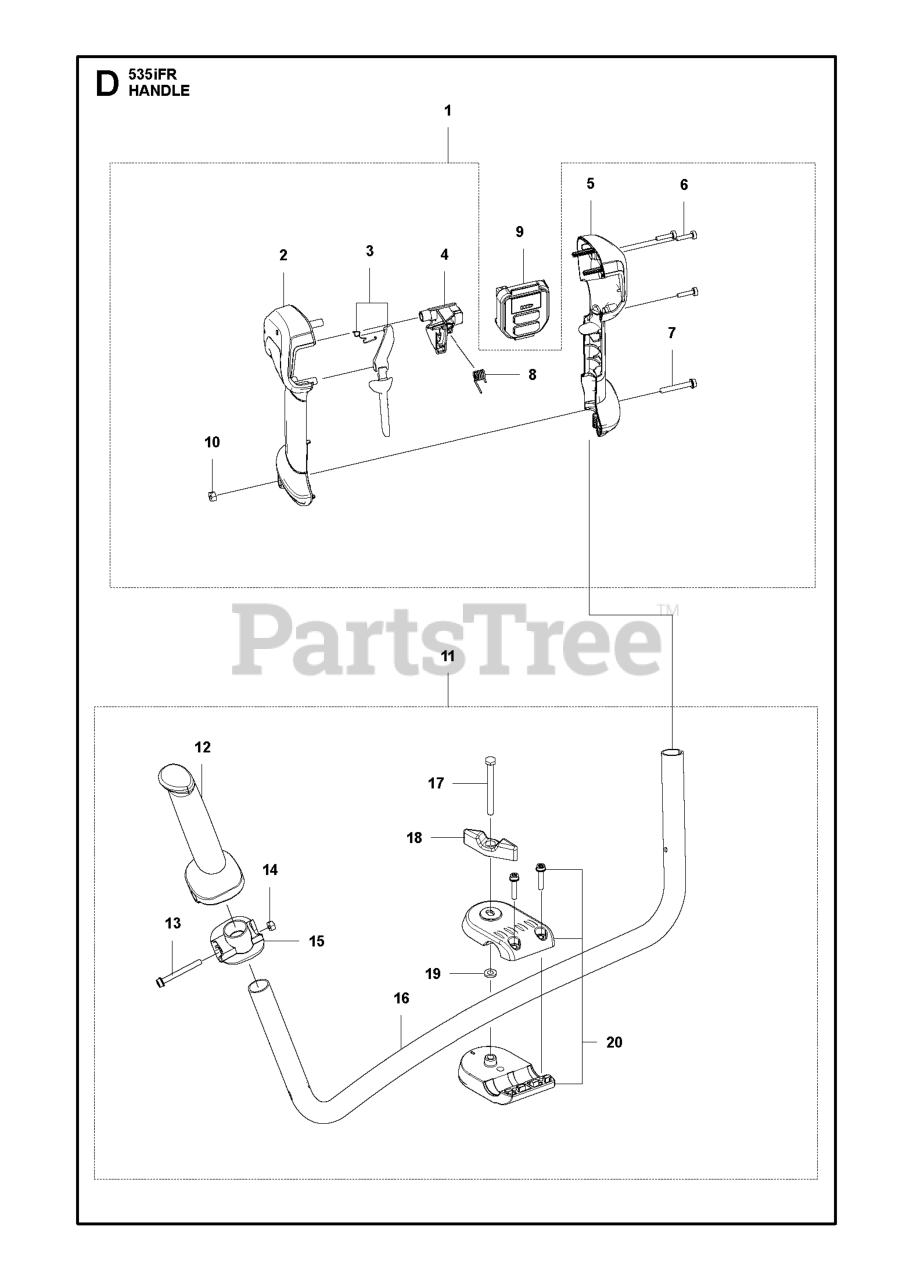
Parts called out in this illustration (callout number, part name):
4	THROTTLE CONTROL ASSY
5	HANDLE HALF RIGHT
6	SCREW ITXSCT PW4.2X18 10.9 ZN
8	SPRING THROTTLE CONTROL
9	Controls
9	CONTROL PANELS
13	SCREWS
